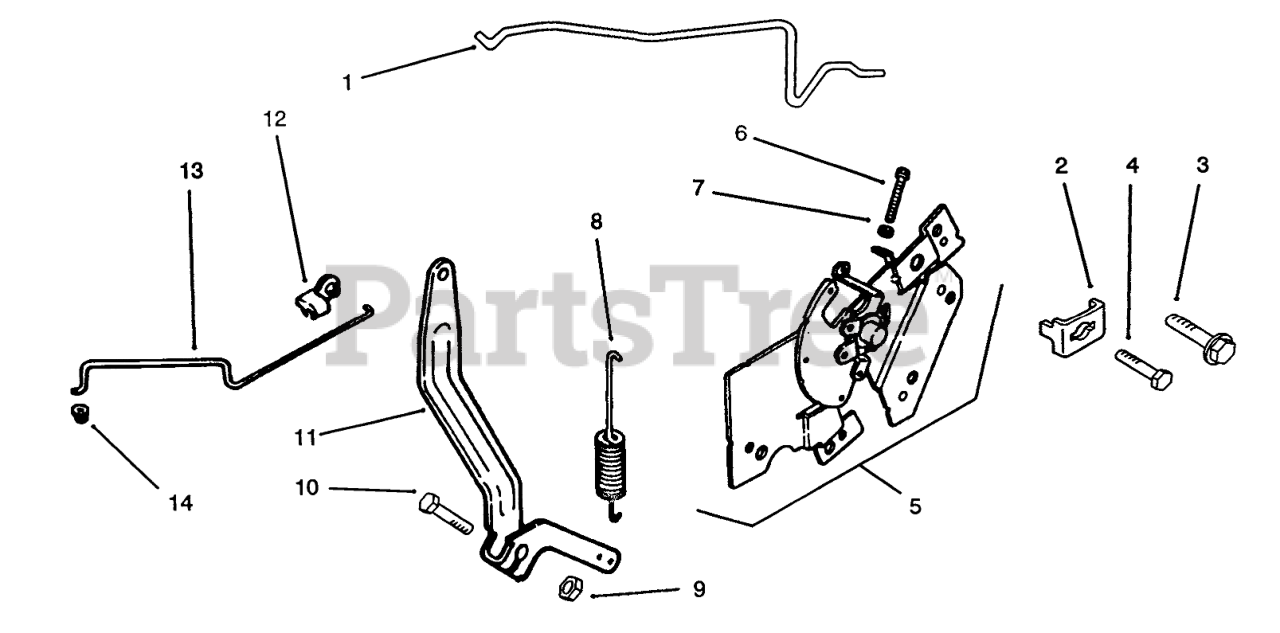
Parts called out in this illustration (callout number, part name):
1	Linkage-Choke (Only On: 72042, 72063, 72062, 72043)
2	Clamp-Cable (Only On: 72042, 72063, 72062, 72043)
3	Screw-HH (Only On: 72042, 72063, 72362, 72043)
4	Screw M5x0.8x16 (Only On: 72042, 72063, 72062, 72043)
5	Control-ASM INC 6-7 (Only On: 72042, 72063, 72062, 72043)
6	Screw-HHF M4x0.7x28 (Only On: 72042, 72063, 72062, 72043)
7	Nut-Hex M4x0.7 (Only On: 72042, 72063, 72062, 72043)
8	Spring-Governor (Only On: 72042, 72063, 72062, 72043)
9	Nut M6x1.0 (Only On: 72042, 72063, 72062, 72043)
10	Screw M6x1.0x25 (Only On: 72042, 72063, 72062, 72043)
11	Lever-Governor (Only On: 72042, 72063, 72062, 72043)
12	Bushing-Linkage (Only On: 72042, 72063, 72062, 72043)
13	Linkage-Throttle (Only On: 72042, 72063, 72062, 72043)
14	Bushing-Linkage (Only On: 72042, 72063, 72062, 72043)
